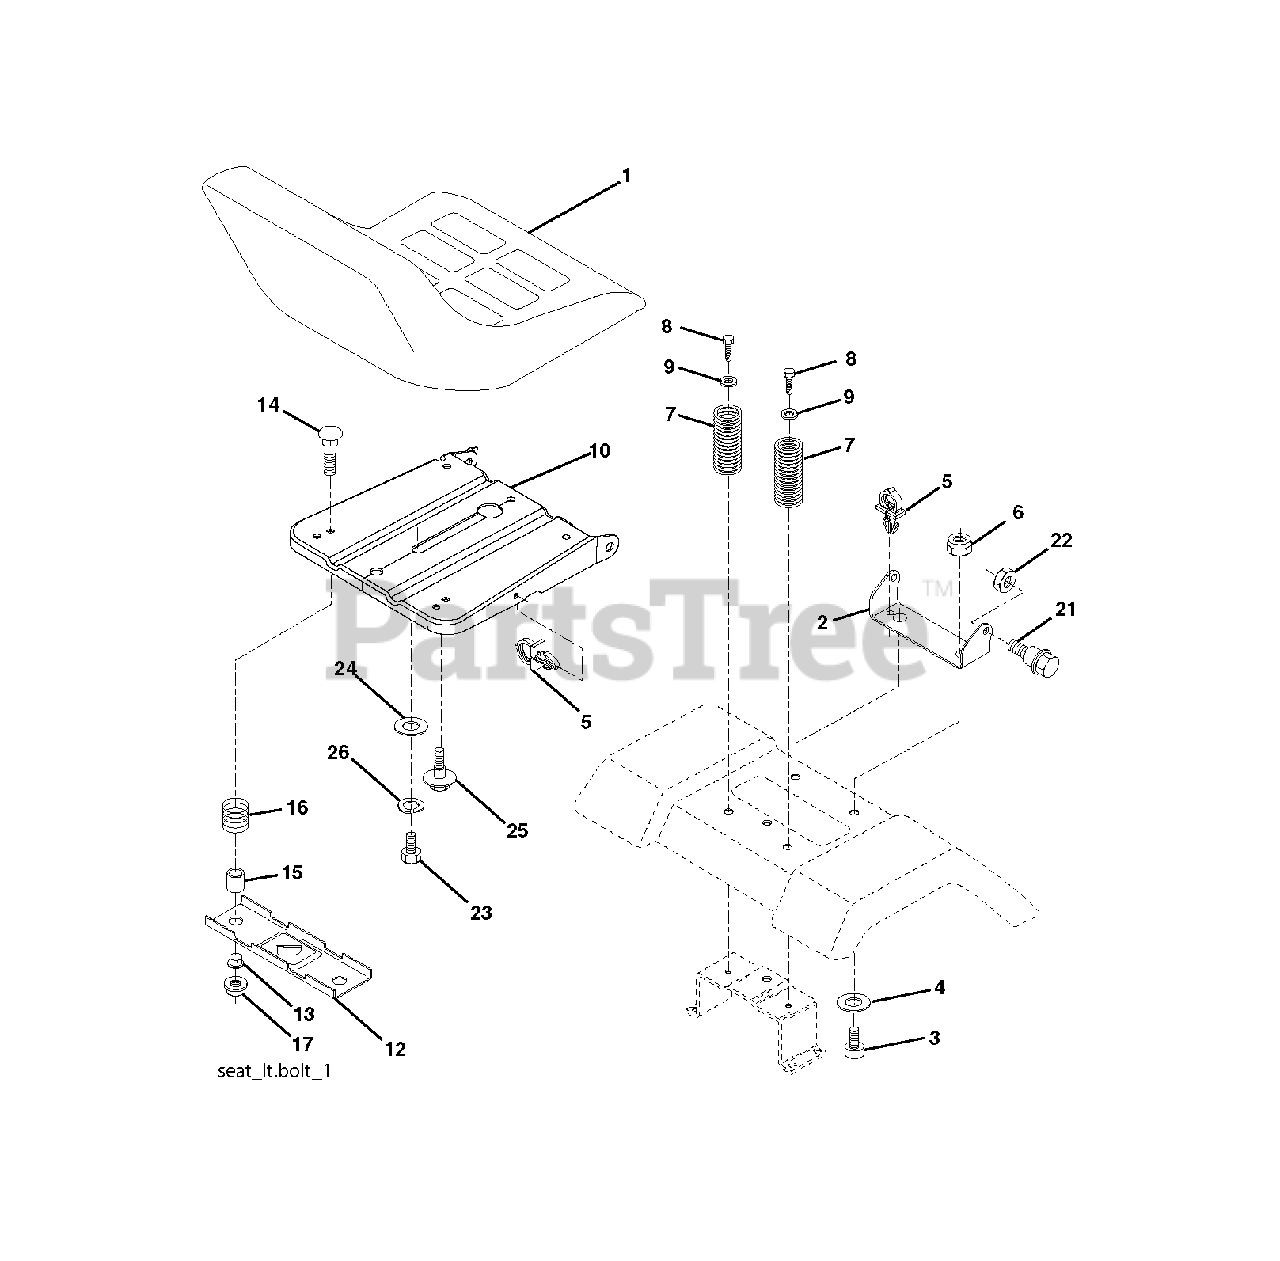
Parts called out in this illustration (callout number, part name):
1	SEAT.XG090.BLK.KB/BLT.NO-LOG
2	SEAT PIVOT BRKT
3	BOLT, HEX 3/8-16X1
6	NUT
7	SPRING COMPRESSION
8	SCREW 3/8-16X1
9	WASHER
10	PAN.ASM.SEAT.1SLOT
12	BRKT.MNTNG.SWITCH.SEAT
14	BOLT.ROUND.HEAD.SQUARE.NECK
15	SPACER SPLIT 28X.96
17	NUT T
21	BOLT.SHOULDER.5/16-18
22	NUT.71038.31-18.HEX.NYLOCK
23	BOLT.HEX.BLACK
